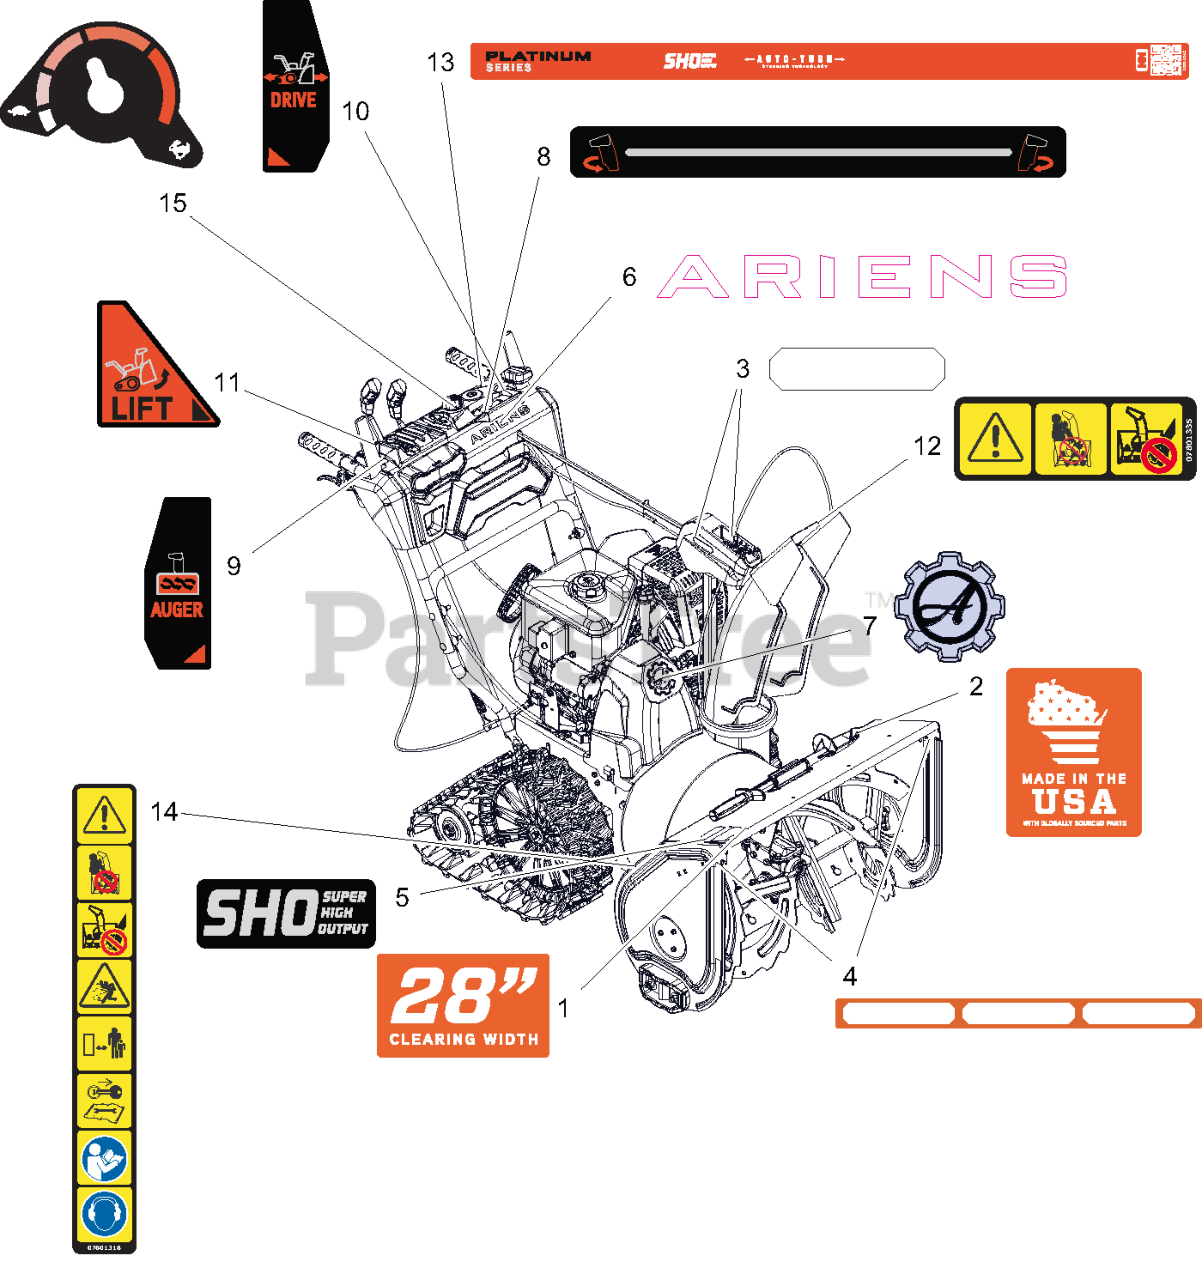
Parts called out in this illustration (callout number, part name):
1	DECAL- CLEARING - 28
2	DECAL- MADE IN USA
3	DECAL,REFLECTIVE,GEAR COVER
4	DECAL,REFLECTIVE,HOUSING
5	DECAL, SHO
6	DECAL- ARIENS - 7.46"
7	DECAL- ARIENS GEAR BADGE
8	DECAL- CHUTE ROTATION
9	DECAL- CONTROL - AUGER
10	DECAL- CONTROL - DRIVE TRACK
11	DECAL- CONTROL - TRACK LIFT
12	DECAL- DANGER
13	DECAL- DASH - PLT RT EFI
14	DECAL- SAFETY - DANGER
15	DECAL- CONTROL - EFI SPEED
